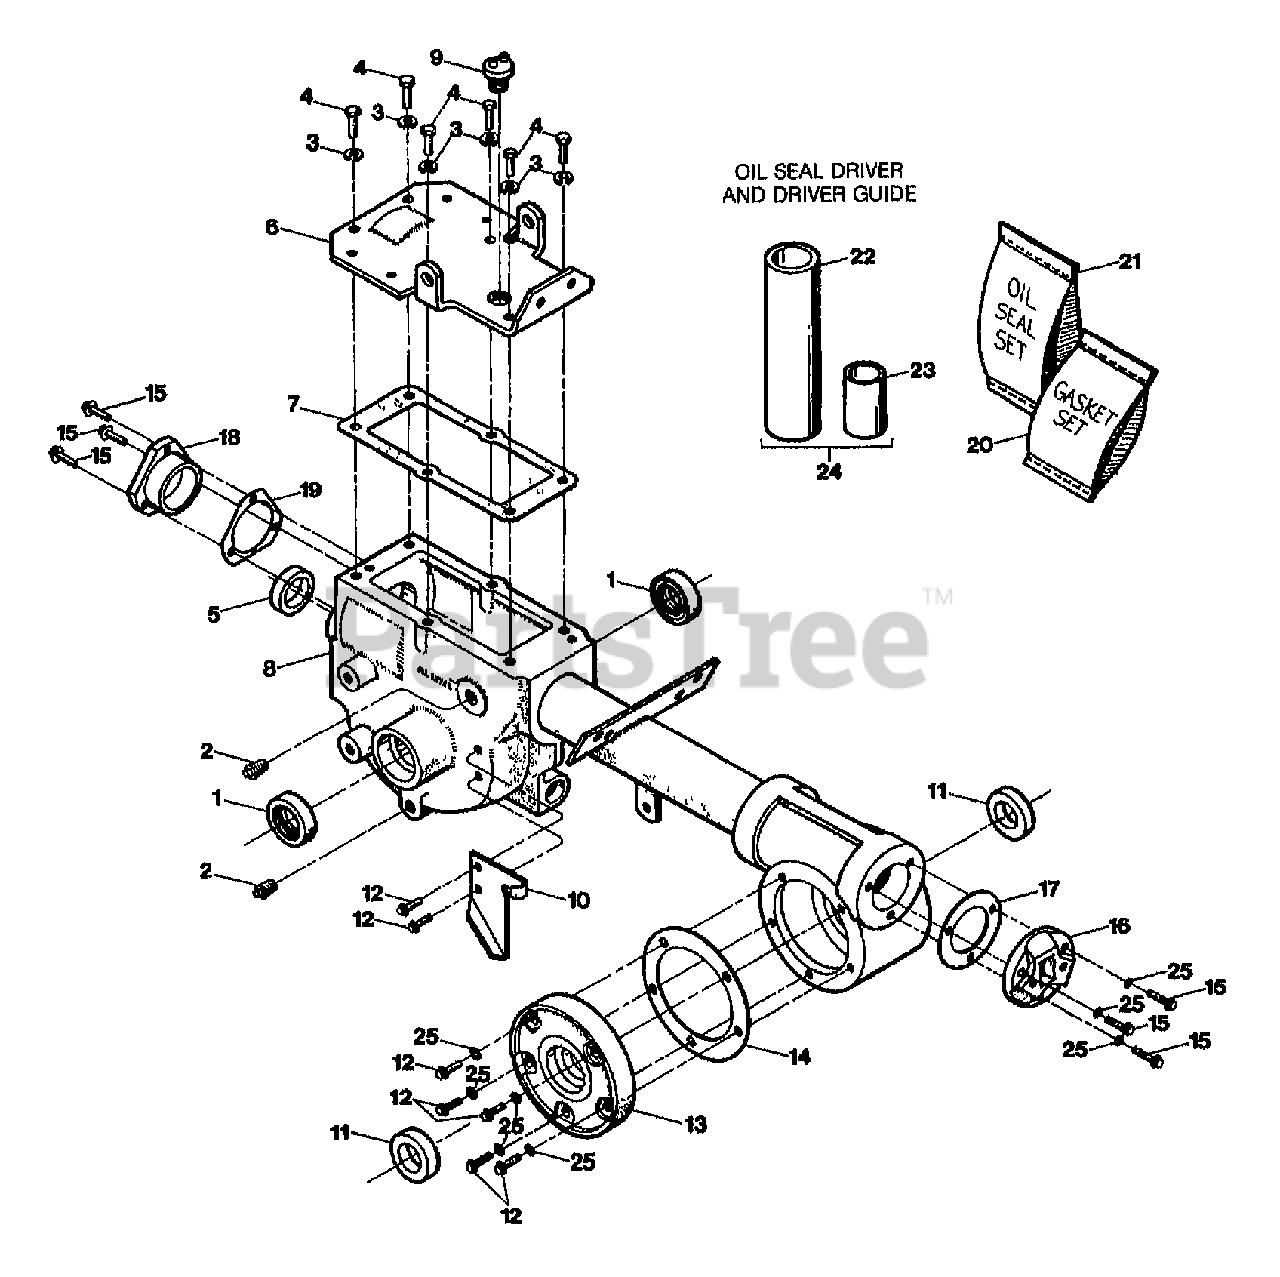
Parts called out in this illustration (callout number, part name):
1	SEAL-OIL WHEELSHAFT
2	PLUG-PIPE 1/4 NPT
3	WASHER-LK .312 ZP
4	SCR-HHC 5/16-18X.75 GR 5 ZP
5	SEAL-PINION SHAFT PT/85030/00
6	COVER-TRANS
7	GASKET-TRANS COVER
8	HSG-TRANS P5 A UNIT (INCL. ONE #9429 REAR BEARING RACE)
9	PLUG-OIL FILL 3/4-10
10	PLATE-CABLE MOUNT PNT (FOR WHEEL DRIVE CABLE)
11	SEAL-TILLER SHAFT
12	SCR-HH 1/4-20X.625
13	COVER-RTH W/SCRS&RACE
14	GASKET-TILLER COVER (FITS ALL COVERS)
15	SCR-HFLK 1/4-20X.875
16	CAP-REAR #1115
17	GASKET-BRG COVER
18	COVER-FRONT BEARING
19	GASKET-FRONT COVER-.010
20	GASKET SET-P4
21	OIL SEAL SET-PONY V
22	DRIVER-PLASTIC (USE W/PART # 4921-2)
23	SEAL-DRIVER PILOT (USE W/PART # 4921-1)
24	KIT-DRIVER
25	WASHER - NYLON, NON REUSEABLE (SEE WASHER KIT)
